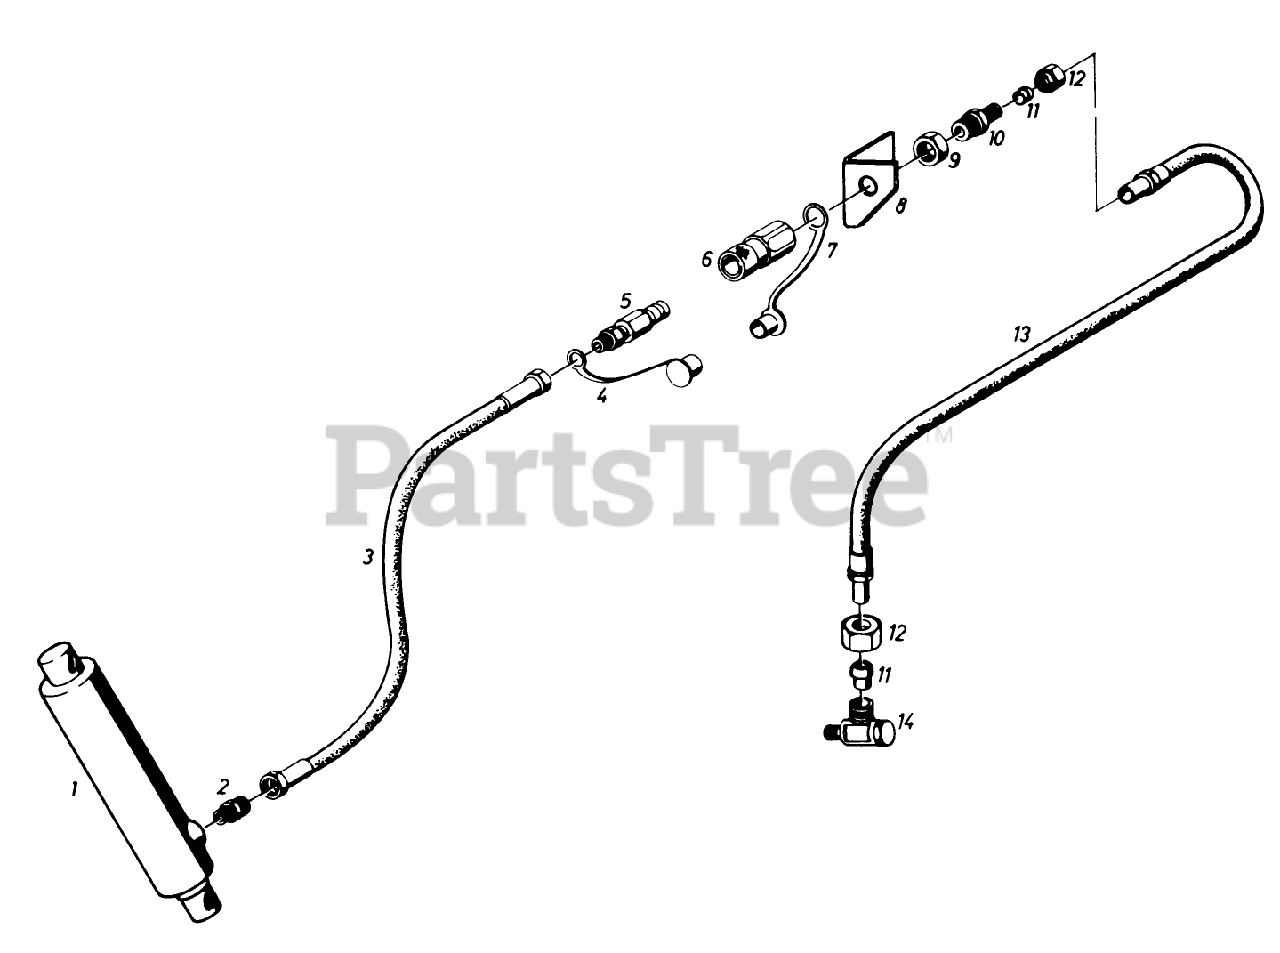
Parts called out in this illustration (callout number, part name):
1	Hydraulic Cylinder
2	FITTING
3	Hydraulic Hose
4	DUST CAP
5	Coupling Plug
6	Q.D. Fitting
7	Dust Cap
8	Mounting Plate
10	Fitting
11	RING SEAL
14	JOINT (CONSISTS 2 PT
